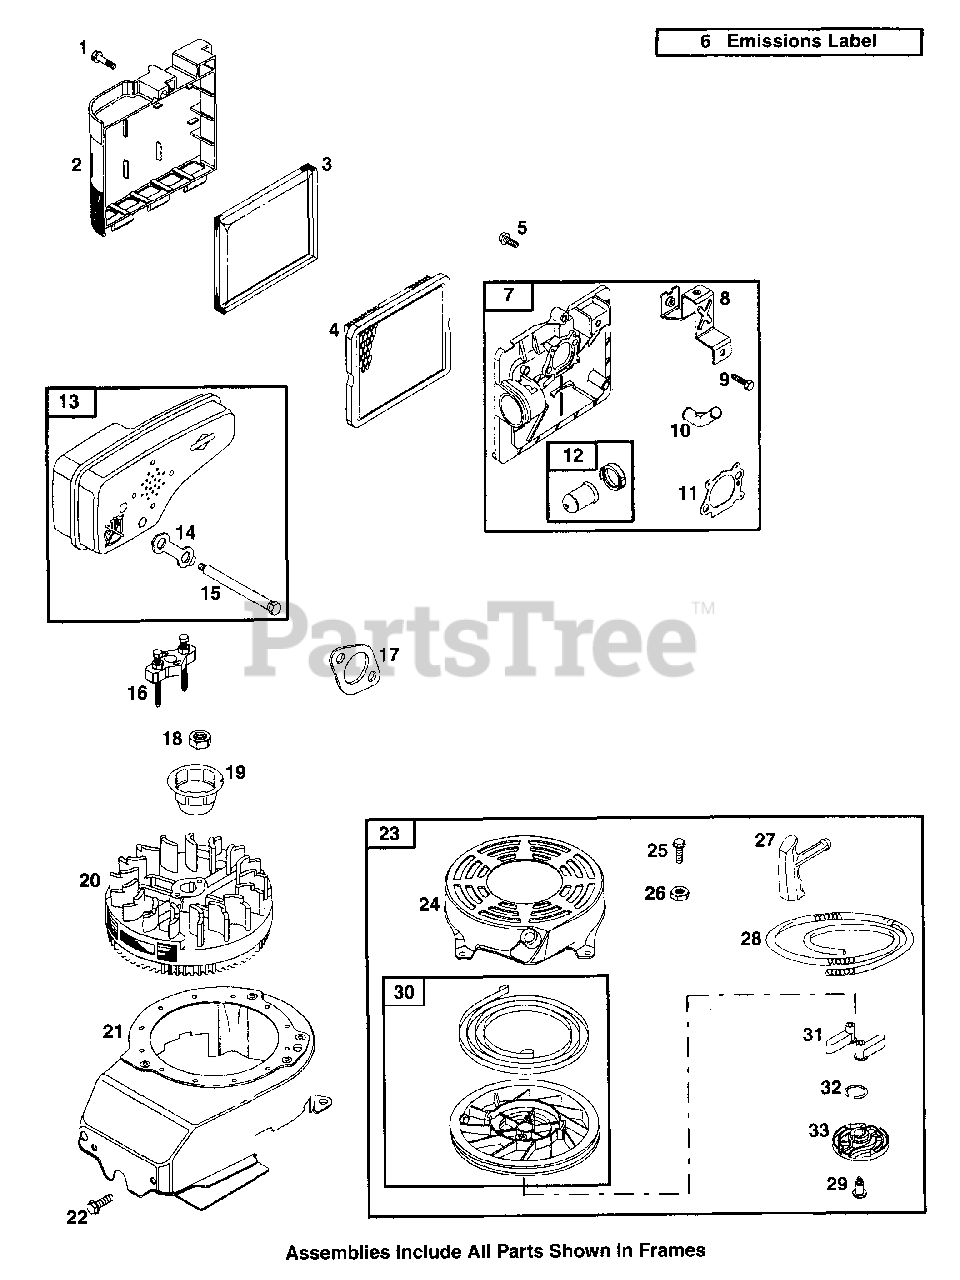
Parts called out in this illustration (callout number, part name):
1	Screw (Air Cleaner Cover)
2	Air Cleaner Cover
3	Pre Cleaner Filter
4	Air Cleaner Cartridge Filter
5	Screw (Air Cleaner Primer Base)
6	Emissions Label
7	Air Cleaner Primer Base
8	Air Cleaner Primer
9	Screw (Air Cleaner Primer Bracket)
11	Air Cleaner Gasket
12	Carburetor Primer
13	Exhaust Muffler
14	Muffler Screw Lock
15	Screw (Exhaust Muffler)
16	Flywheel Puller
17	Exhaust Gasket
18	Nut (Flywheel)
19	Flywheel Cup
21	Blower Housing
22	Screw (Blower Housing)
23	Rewind Starter
24	Rewind Starter Housing
26	Nut (Rewind Starter)
27	Starter Rope Grip
28	Starter Rope
29	Screw (Pawl Friction Plate)
30	Pulley/Spring Assembly
31	Ratchet Plate
32	Friction Spring
33	Pawl Friction Plate
